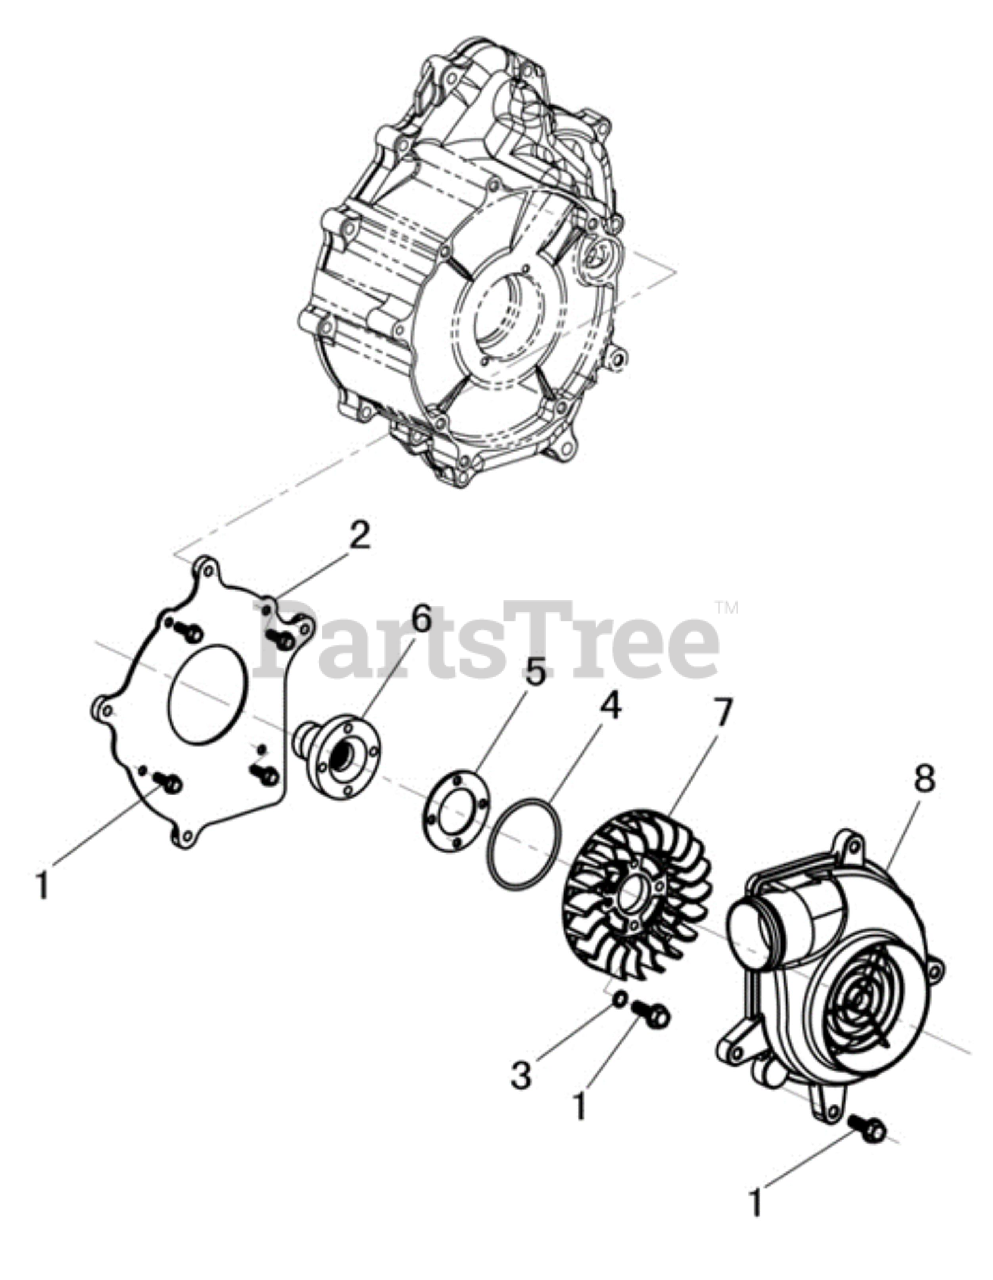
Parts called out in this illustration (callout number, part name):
1	Hexagon flange bolts M6X20
3	Washer 6X11X1.5
4	O-Ring 64.4X3.1
5	Fan Strongback
6	Starting Driven Pulley
8	Fan Cowl
